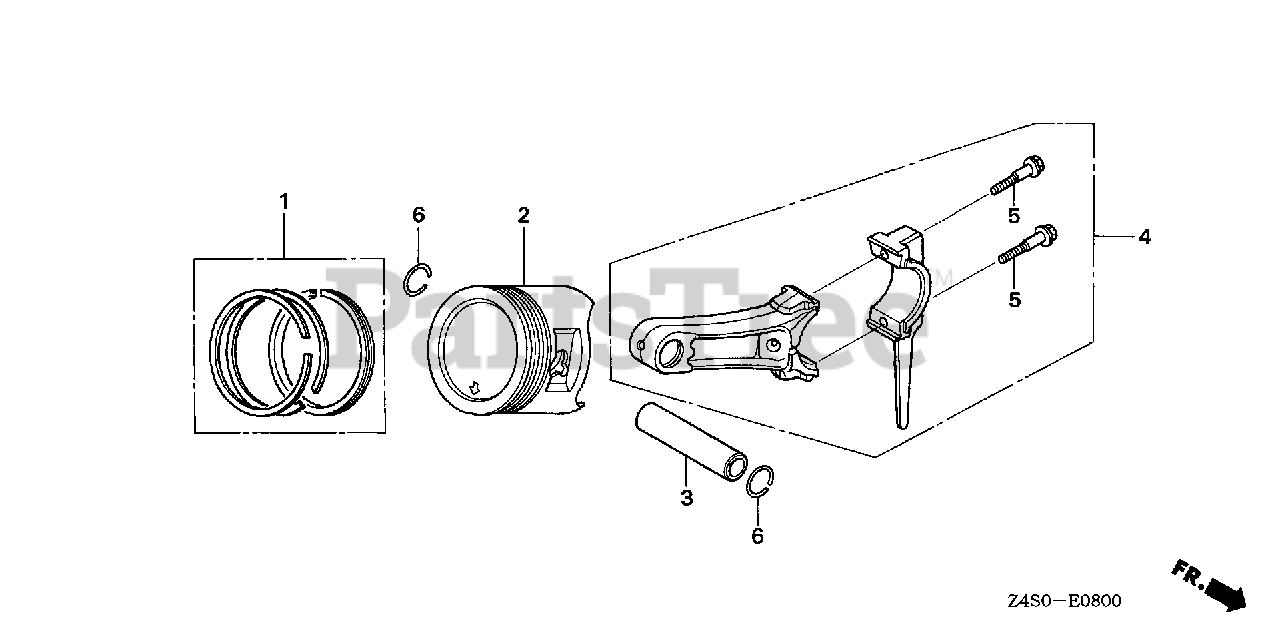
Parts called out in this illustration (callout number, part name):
1	RING SET, PISTON (STD) (TEIKOKU)
1	RING SET, PISTON (STD.) (NIPPON)
1	RING SET, PISTON (STD) (TPR)
1	RING SET, PISTON (OS 0.25) Use from Engine SN 7603339.
1	RING SET, PISTON (0.25) (NIPPON) Use up to Engine SN 1314912.
1	RING SET, PISTON (0.25) Use from Engine SN 1314913.
1	RING SET, PISTON (OS 0.50) Use from Engine SN 7603339.
1	RING SET, PISTON (0.50) (NIPPON) Use up to Engine SN 1314912.
1	RING SET, PISTON (0.50) (TPR)
1	RING SET, PISTON (0.75) (TEIKOKU) Use up to Engine SN 1314912.
1	RING SET, PISTON (0.75) (NIPPON) Use up to Engine SN 1314912.
1	RING SET, PISTON (0.75) Use from Engine SN 1314913.
2	PISTON (STD)
2	PISTON (OS 0.25) Use from Engine SN 1645602.
2	PISTON (0.25)
2	PISTON (OS 0.50)
2	PISTON (0.50)
2	PISTON (0.75) Use from Engine SN 1645602.
2	PISTON (0.75)
3	PIN, PISTON
4	ROD ASSY., CONNECTING
5	BOLT, CONNECTING ROD
6	CLIP, PISTON PIN (18MM)
